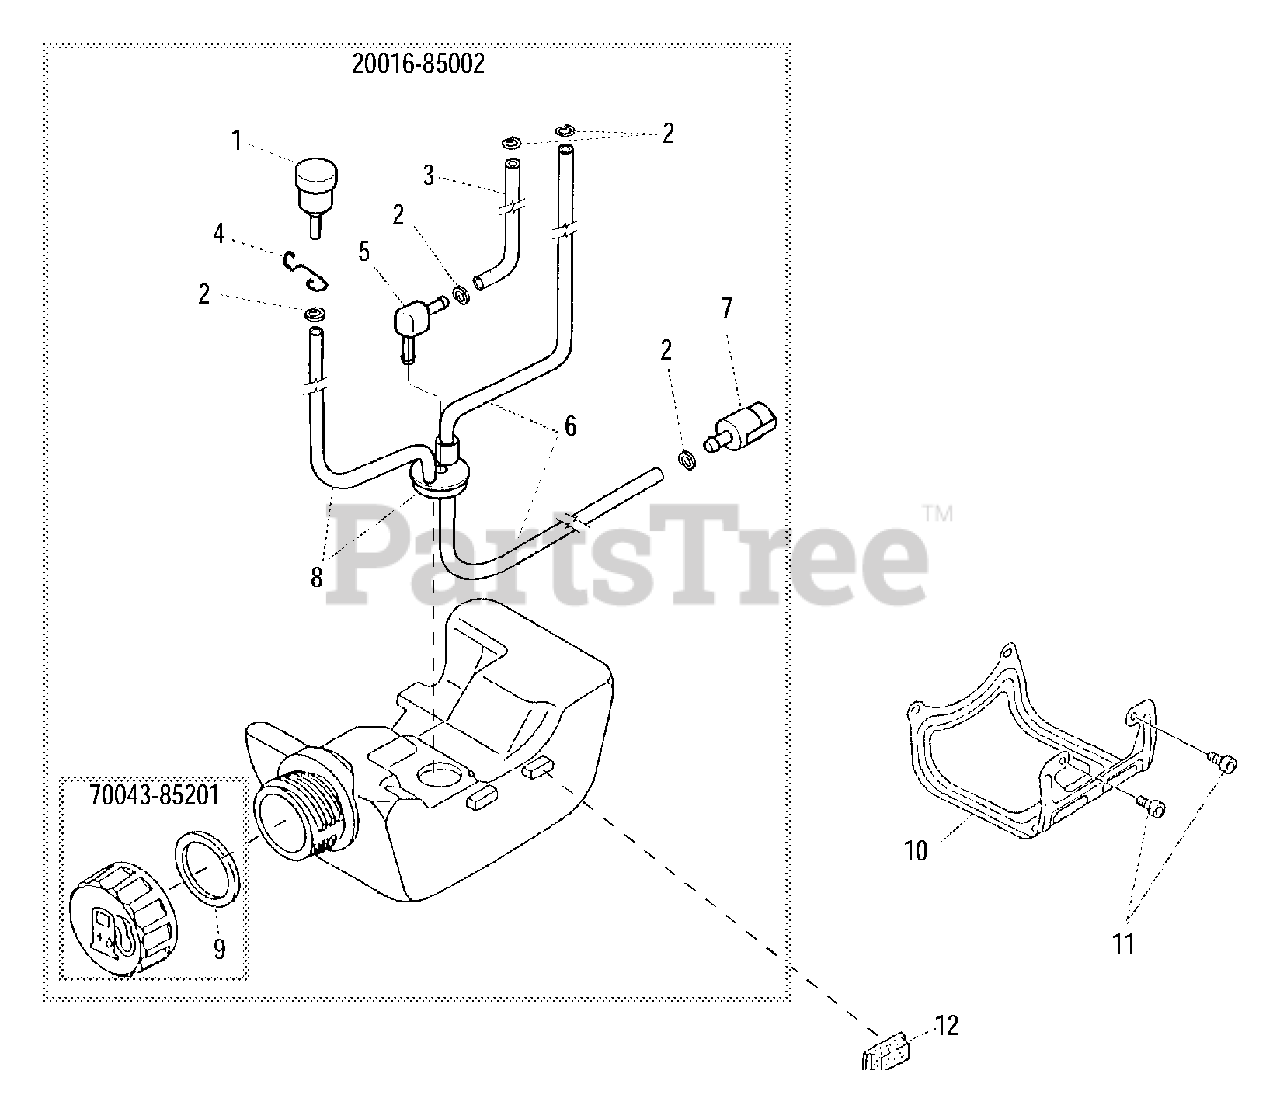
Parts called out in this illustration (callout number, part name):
1	VENT, FUEL TANK
2	RING, RETAINING - 6
3	PIPE - RETURN
4	HOLDER, VENT
5	CONNECTOR, PIPE
6	PIPE - FUEL
7	FILTER, FUEL
8	GROMMET
9	GASKET, CAP
10	GUARD, FUEL TANK
11	SCREW - 5X12
12	CUSHION, TANK
20016-85002	FUEL TANK ASSY
70043-85201	CAP ASSY
